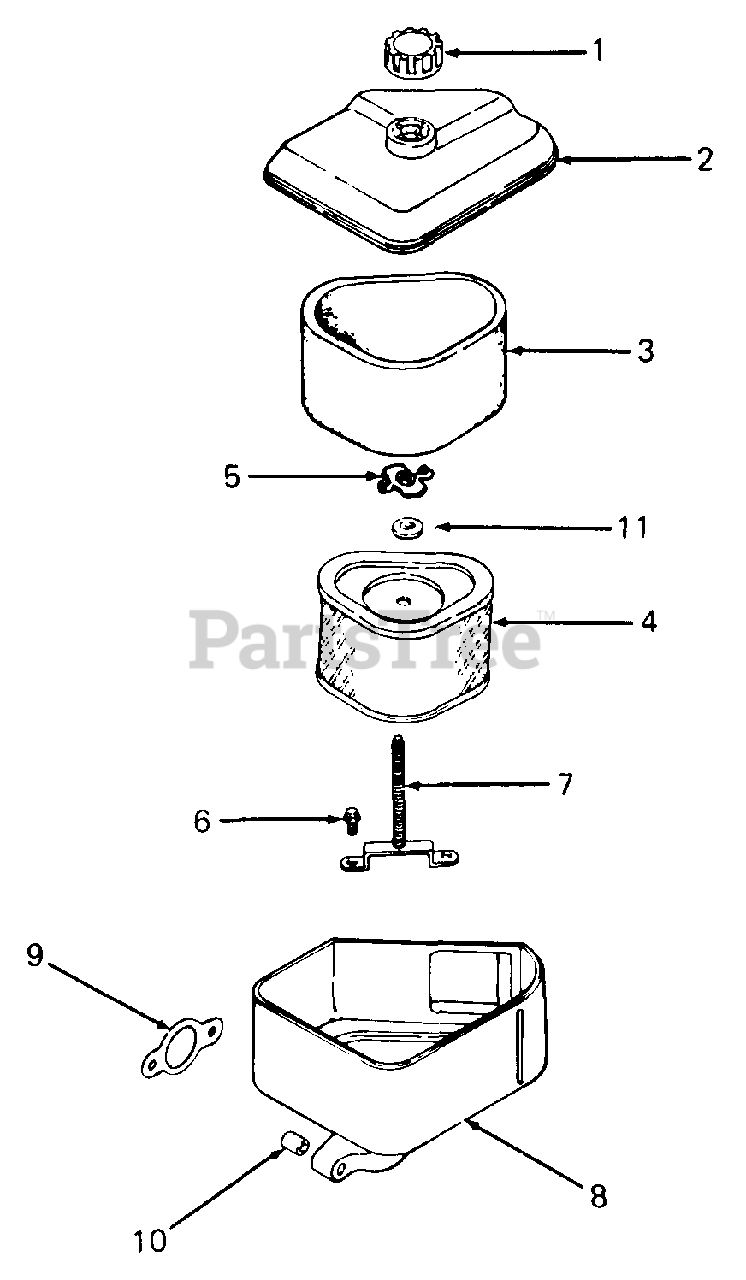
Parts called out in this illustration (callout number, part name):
1	Knob, Air Cleaner Cover
2	Cover, Air Cleaner
3	Precleaner, Element
4	Element, Air Cleaner
6	Screw, Mtg Plate Stud
7	Stud, Mounting Plate
8	Base, Air Cleaner
9	Gasket, Air Cleaner
11	Washer, Plain, 1/4
